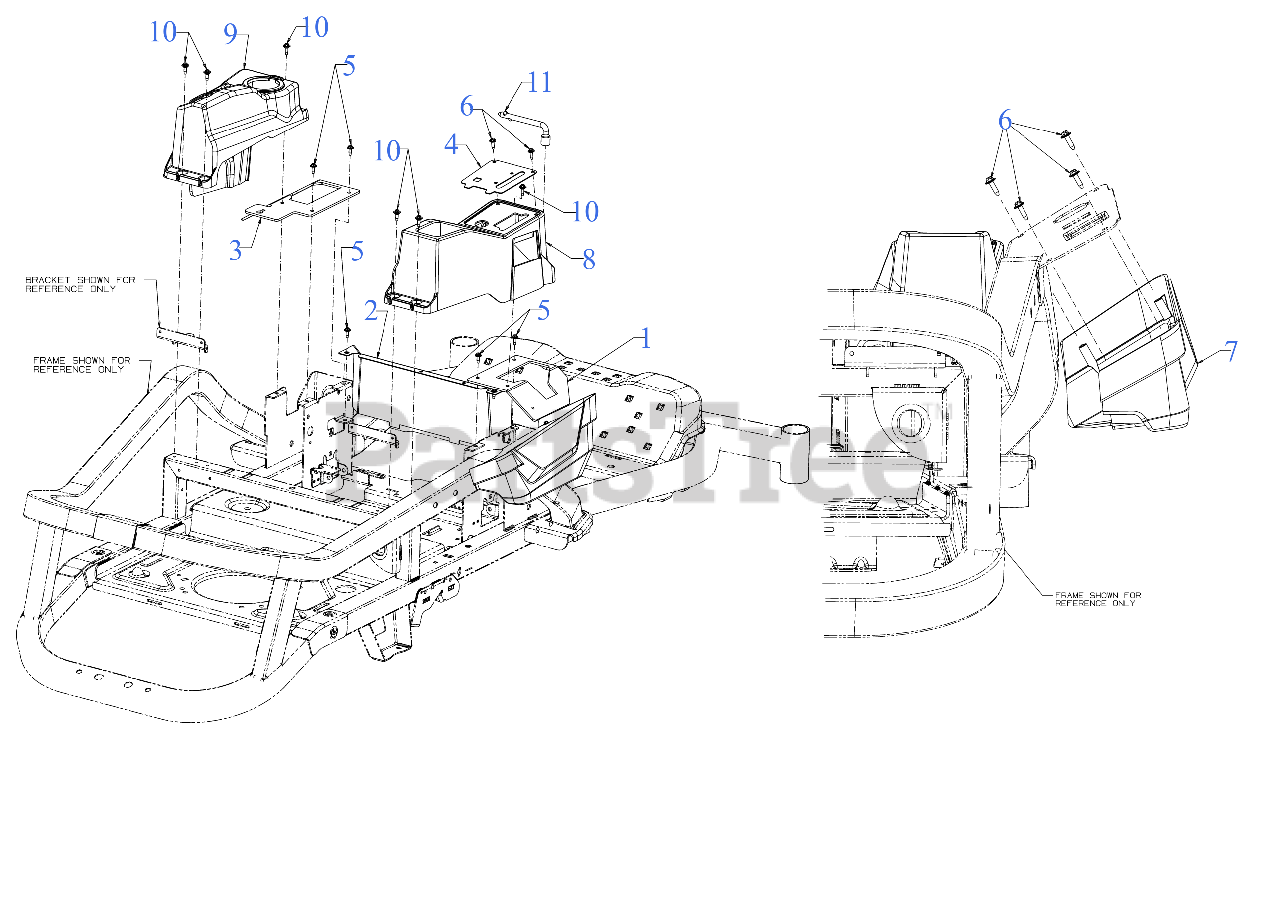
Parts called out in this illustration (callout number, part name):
1	CONTROL BRACKET (RH)
2	SEAT BOX FRONT PLATE
3	CONTROL BRACKET (LH)
4	THROTTLE COVER
5	SCREW M6-1 x .625
6	SCREW 1/4-10 x .750
7	CONTROL PANEL CONSOLE
8	CONSOLE (RH)
9	CONSOLE (LH)
10	SHOULDER SCREW M6-1 .368 X.115
11	MULTI TOOL-1/2" SOCKET
